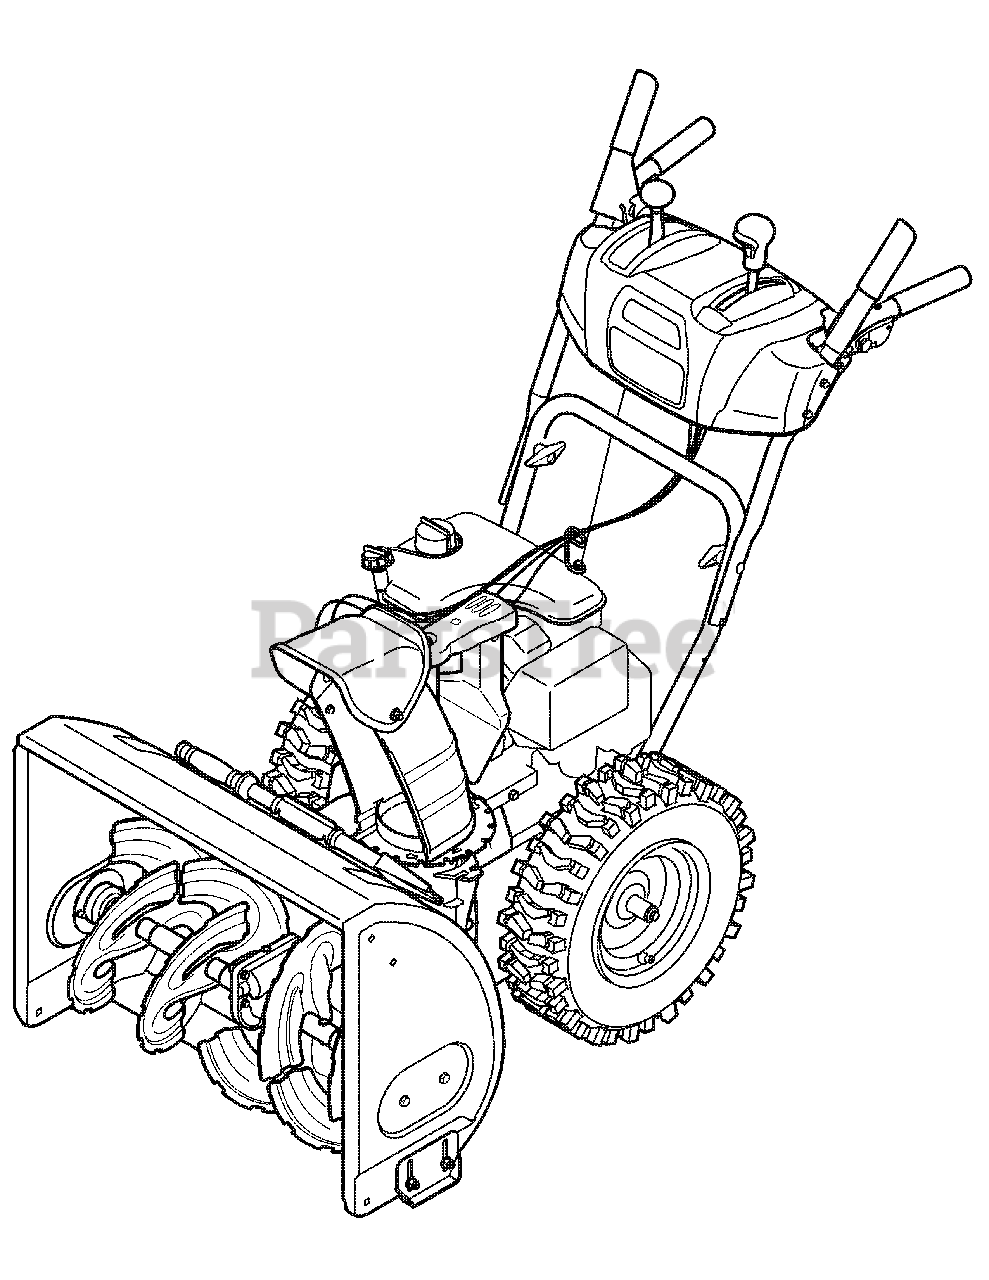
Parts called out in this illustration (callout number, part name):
NA	Lamp
NA	Spiral Crescent
NA	Rubber Paddle
